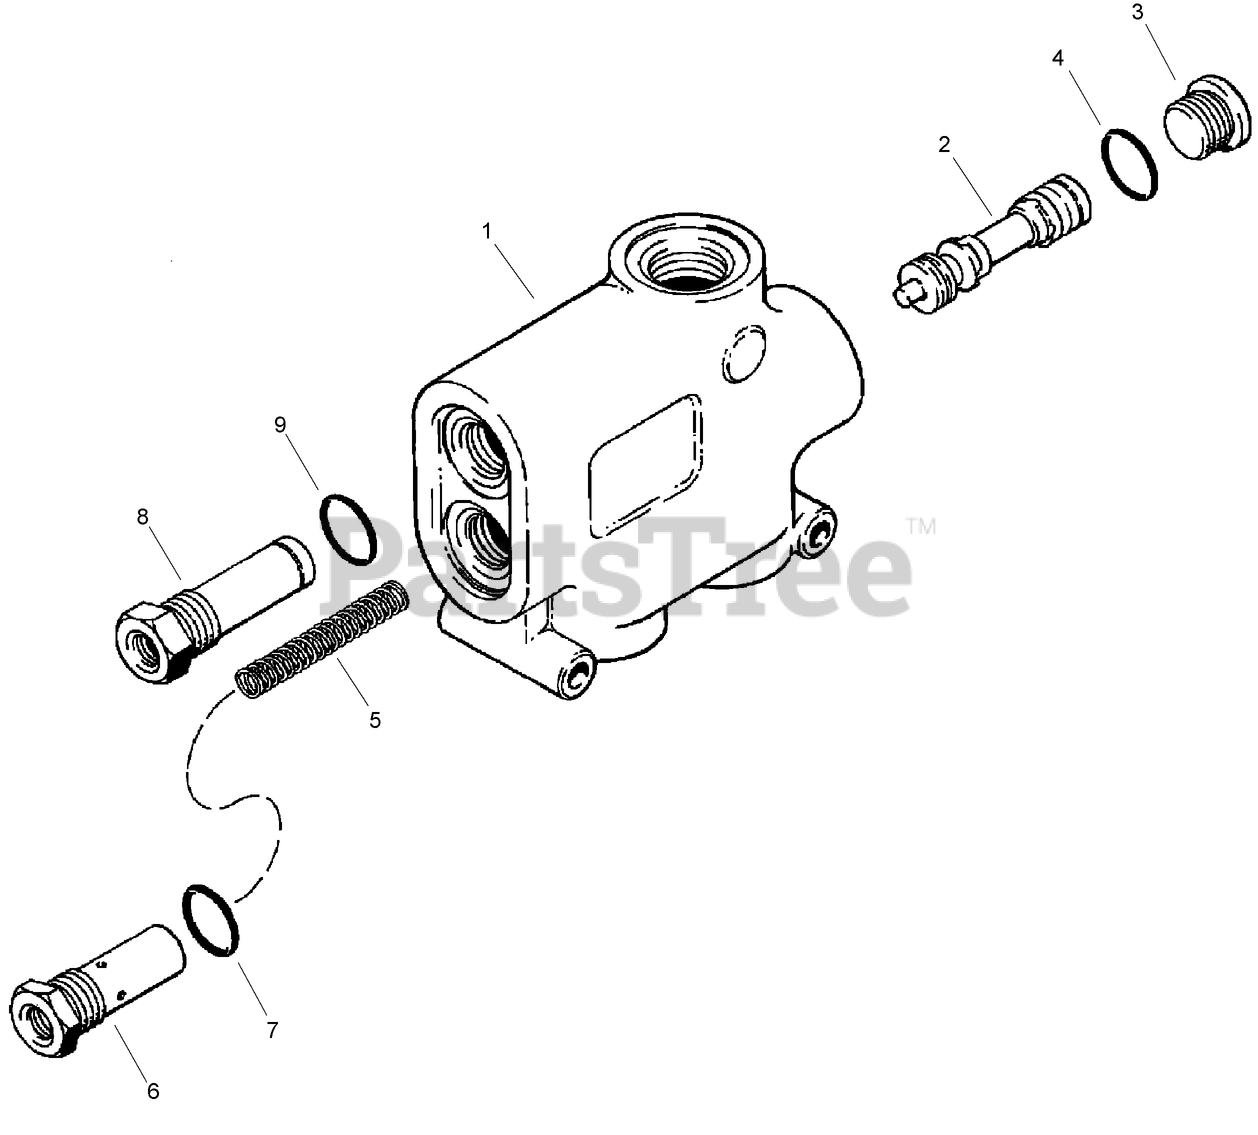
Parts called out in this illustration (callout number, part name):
1	BODY-VALVE
2	SPOOL-Valve
3	PLUG-Spool End
4	O-RING-41/64 ID x 3/32 inch Wide
5	SPRING-SPOOL
6	PLUG-RETAINING, SPOOL SPRING
7	O-RING
8	CARTRIDGE-Relief Valve
9	O-RING-41/64 ID x 3/32 inch Wide
